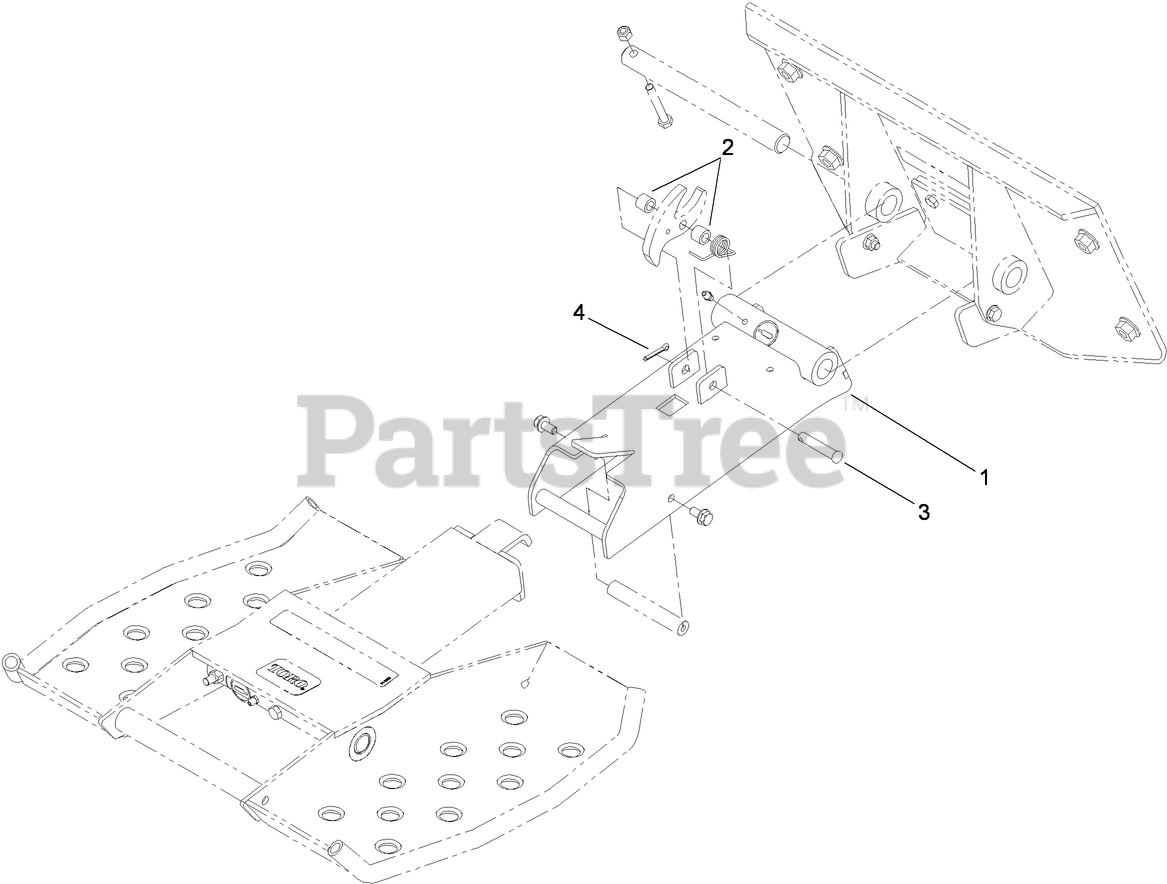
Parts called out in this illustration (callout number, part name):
1	LINKAGE-WRAPPER
2	SPACER
3	PIN-CLEVIS
4	PIN-COTTER
